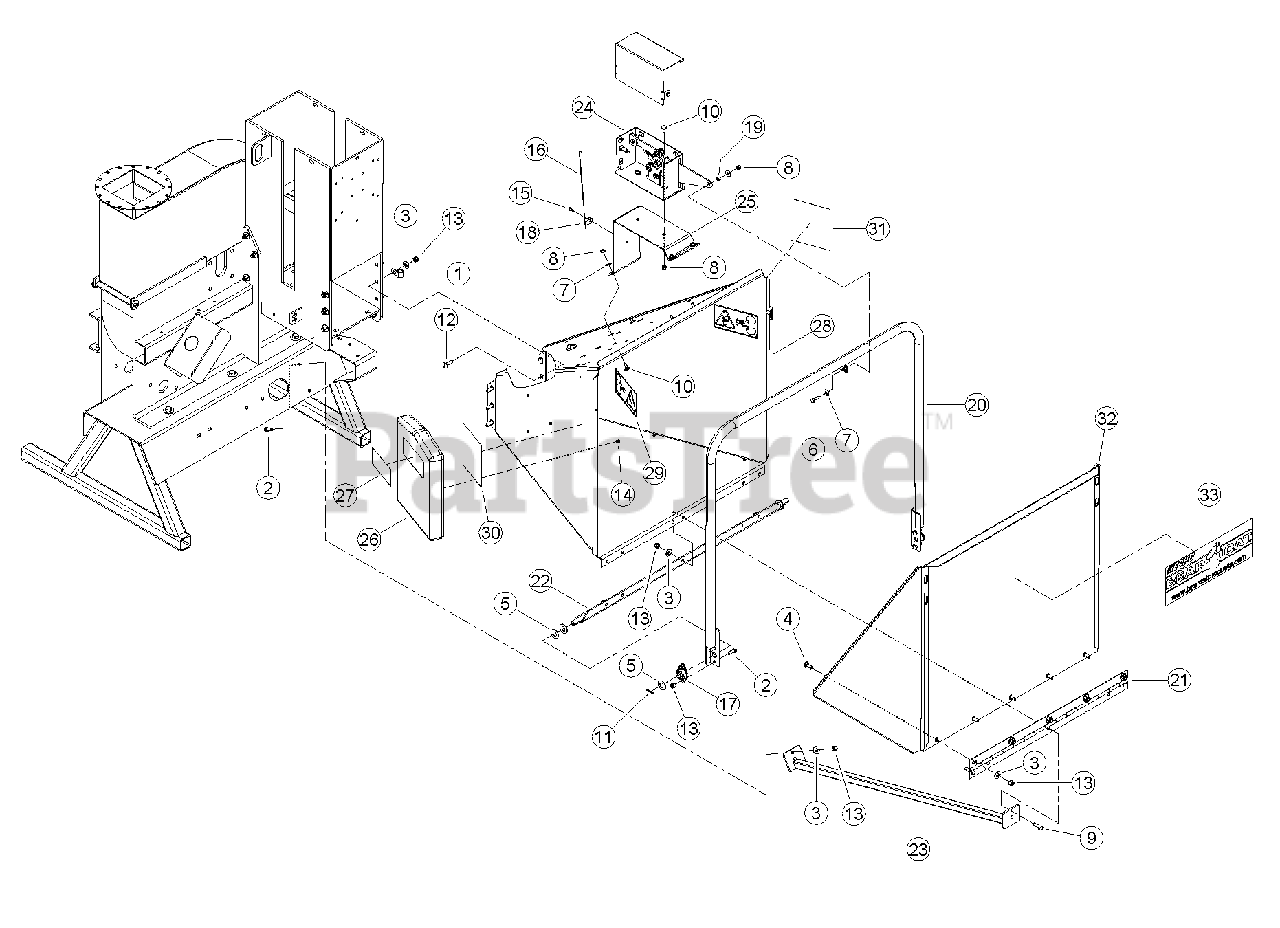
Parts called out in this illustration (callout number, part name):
1	CLAMP, 9/16 COATED
2	BOLT, 3/8 X 1 HEX HD GR5 ZP
3	WASHER, 3/8 FLAT ZP
4	BOLT, 3/8 X 1 CRG GR5 NC ZP
5	WASHER, 5/8 SAE FLAT ZP
6	BOLT, 5/16 X 1 HEX HD GR5 NC ZP
7	WASHER, 5/16 FLAT ZP
8	NUT, 5/16 NE NYLOCK ZP
9	BOLT, 3/8 X 1-1/4 HEX HD GR5 ZP
10	BOLT, 5/16 X 3/4 CRG GR5 NC ZP
11	PIN, 1/8 X 1.00 ZP COTTER
12	BOLT, 3/8 X 1-1/4 CRG GR5 NC ZP
13	NUT, 3/8 NE NYLOCK ZP
14	RIVET, AL BLIND 1/4 X 1/2 DOME HEAD
15	RIVET, AL BLIND 1/4 X 3/4 DOME HEAD
16	STRAP, 11 INCH BLACK TIE
17	BEARING, SIDE FLNG MOUNT 5/8
18	CLAMP, CABLE MOUNT
19	SPACER, IDLER PIVOT
20	WELDMENT, CONTROL ARM
21	HINGE, EXTENSION TRAY
22	WELDMENT, CONTROL PIVOT
23	WELDMENT, CHUTE SUPPORT
24	ASSEMBLY, SWITCH BOX
25	MOUNT, SWITCH BOX
26	ASSEMBLY, MANUAL CONTAINER SERVICE PART
27	DECAL, MUTILINGUAL MANUAL
28	ASSEMBLY, BIG CHIPPER CHUTE SERVICE PART
29	DECAL, BLADE DANGER ISO
30	DECAL, FEED POSITION
31	DECAL, FEED POSITION
32	ASSEMBLY, CHUTE EXTENSION TRAY SERVICE PART
33	DECAL, BEARCAT WEB
